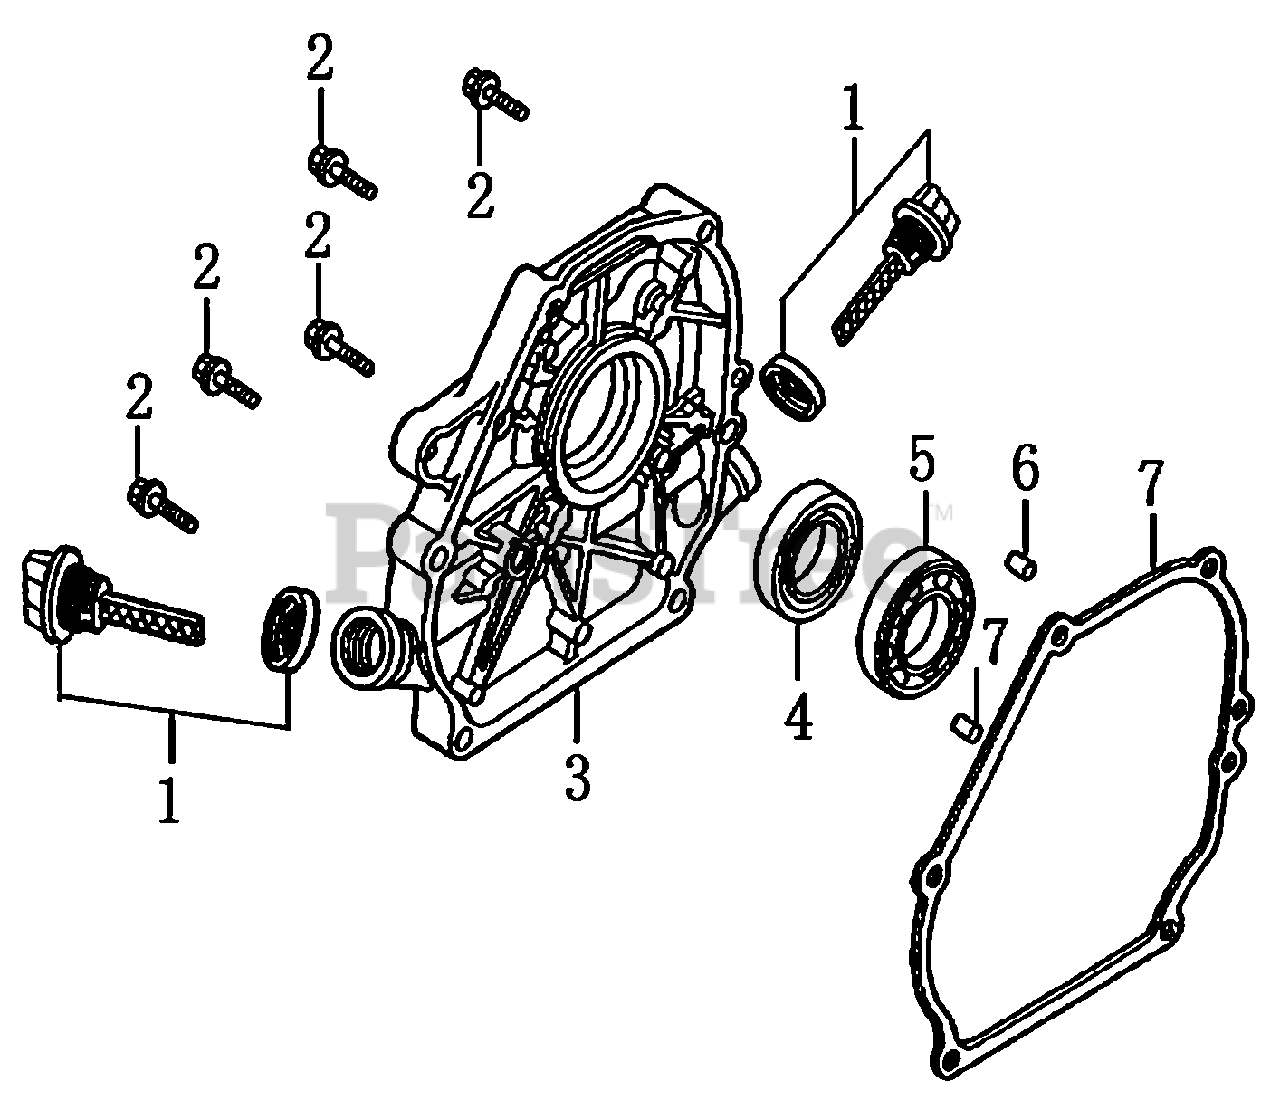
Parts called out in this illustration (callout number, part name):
1	CAP ASSY. DIP STICK
2	BOLT, FLANGE
3	CASE COVER
4	OIL SEAL 25×41.25×6
5	BEARING, RADIAL BALL
6	PIN, DOWEL
7	GASKET, CASE COVER
